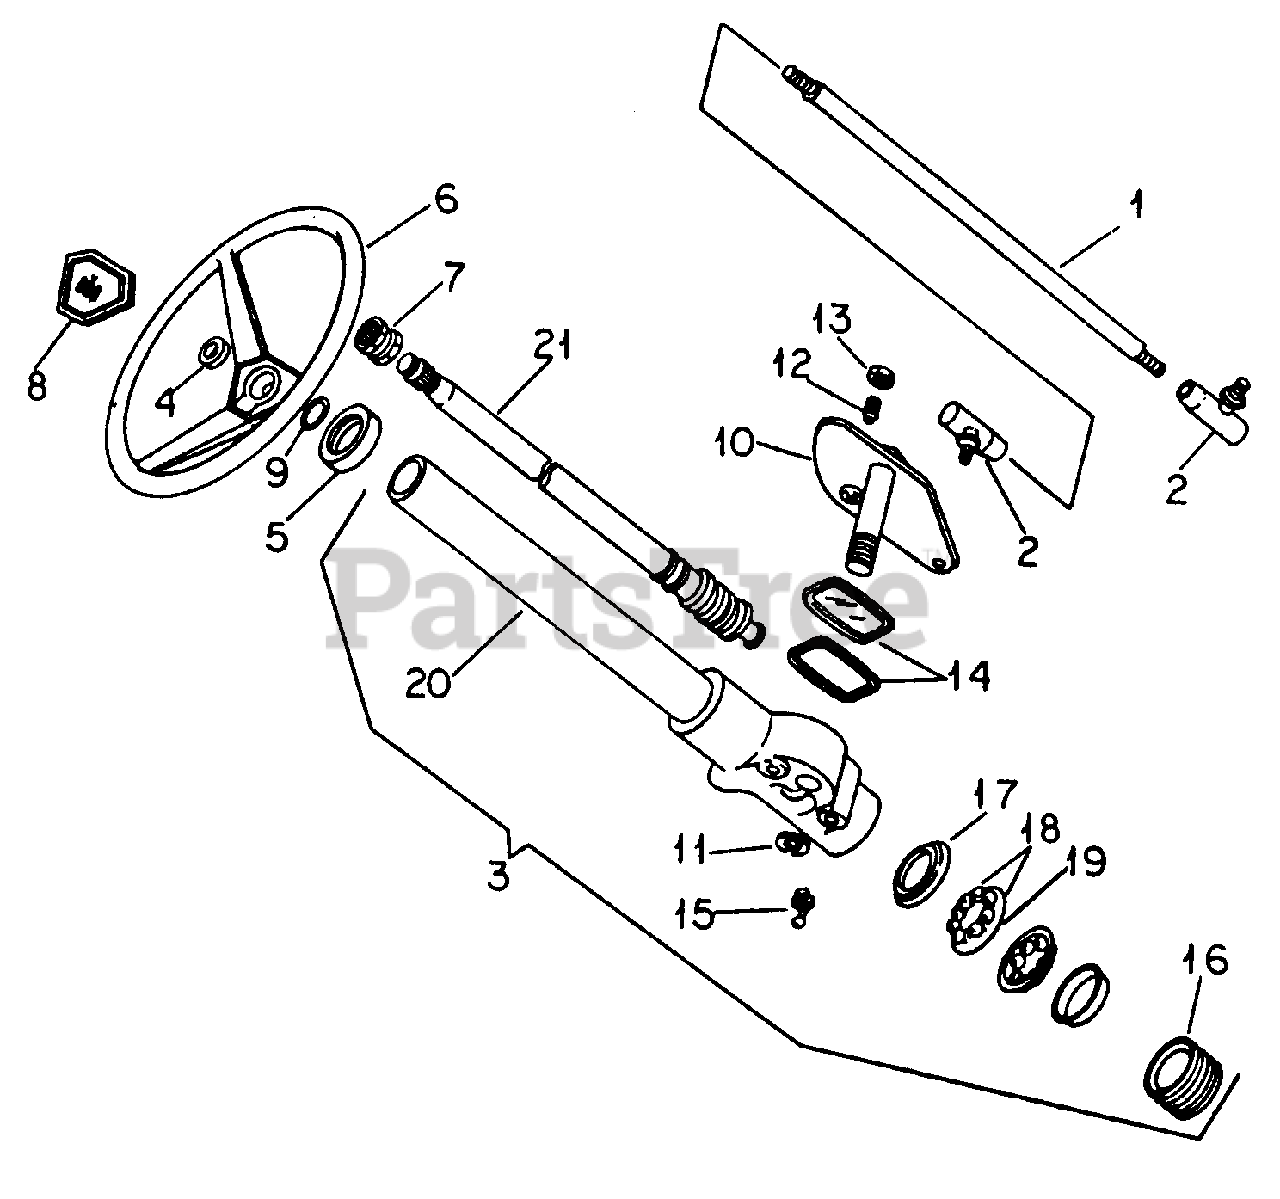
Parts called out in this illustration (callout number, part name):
1	Link, Steering Gear Drag
2	Joint, Ball
3	Gear Assy, Steering
4	Seal, Steering Gear
5	Bearing, Column Upper
6	Wheel Assy, Steering
7	Not used in this application
8	Cap, Steering Wheel
9	O-Ring, 1-3/4 X 1/8
10	Lever & Bolt
11	Washer, Flat - CDP
12	Stud, Cam Follower
13	Nut, 1/2-NF Jam Type 5
14	Package, Seal & Seal Retainer
15	Fitting, 1/4 65 Deg Angle Lub
16	Plug, Adjusting
17	Cup
18	Bearing
19	Retainer, Ball
20	Tube, Housing & Jacket
21	Cam & Tube Assy
